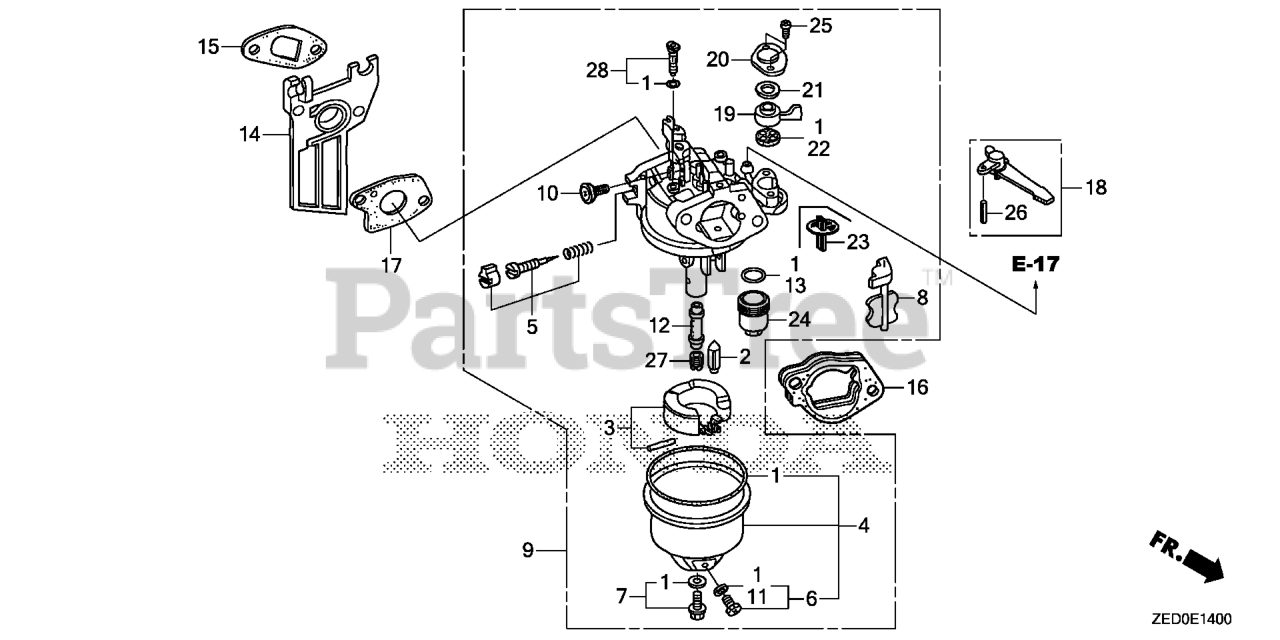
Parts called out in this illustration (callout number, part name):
1	GASKET SET
2	VALVE SET, FLOAT (CARBURETOR NO.) (SEAT NOT INCLUDED)
3	FLOAT SET
4	CHAMBER SET, FLOAT
5	SCREW SET
6	SCREW SET, DRAIN
7	SCREW SET (CARBURETOR NO.)
8	CHOKE SET
9	CARBURETOR ASSY. (BE99N A)
10	SCREW, THROTTLE STOP
11	WASHER, PLAIN (6.2X10.7 DRAIN) (CARBURETOR NO.)
12	NOZZLE, MAIN (CARBURETOR NO.)
13	GASKET, FUEL STRAINER CUP
14	INSULATOR, CARBURETOR
15	GASKET, INSULATOR
15	GASKET, INSULATOR (NINGBO SIL GASKET)
16	SPACER, CARBURETOR
17	GASKET, CARBURETOR
17	GASKET, CARBURETOR (NINGBO SIL GASKET)
18	LEVER, CHOKE (STD)
19	LEVER, VALVE
20	PLATE, LEVER SETTING (CARBURETOR NO.)
21	SPRING, PETCOCK LEVER (CARBURETOR NO.)
22	GASKET, VALVE
23	FILTER, CUP (CARBURETOR NO.)
24	CUP, FUEL STRAINER
25	SCREW, PAN (3X6)
26	PIN, SPRING (2X12)
27	JET, MAIN (#65)
27	JET, MAIN (#68)
27	JET, MAIN (#70)
28	JET SET, PILOT (#38)
